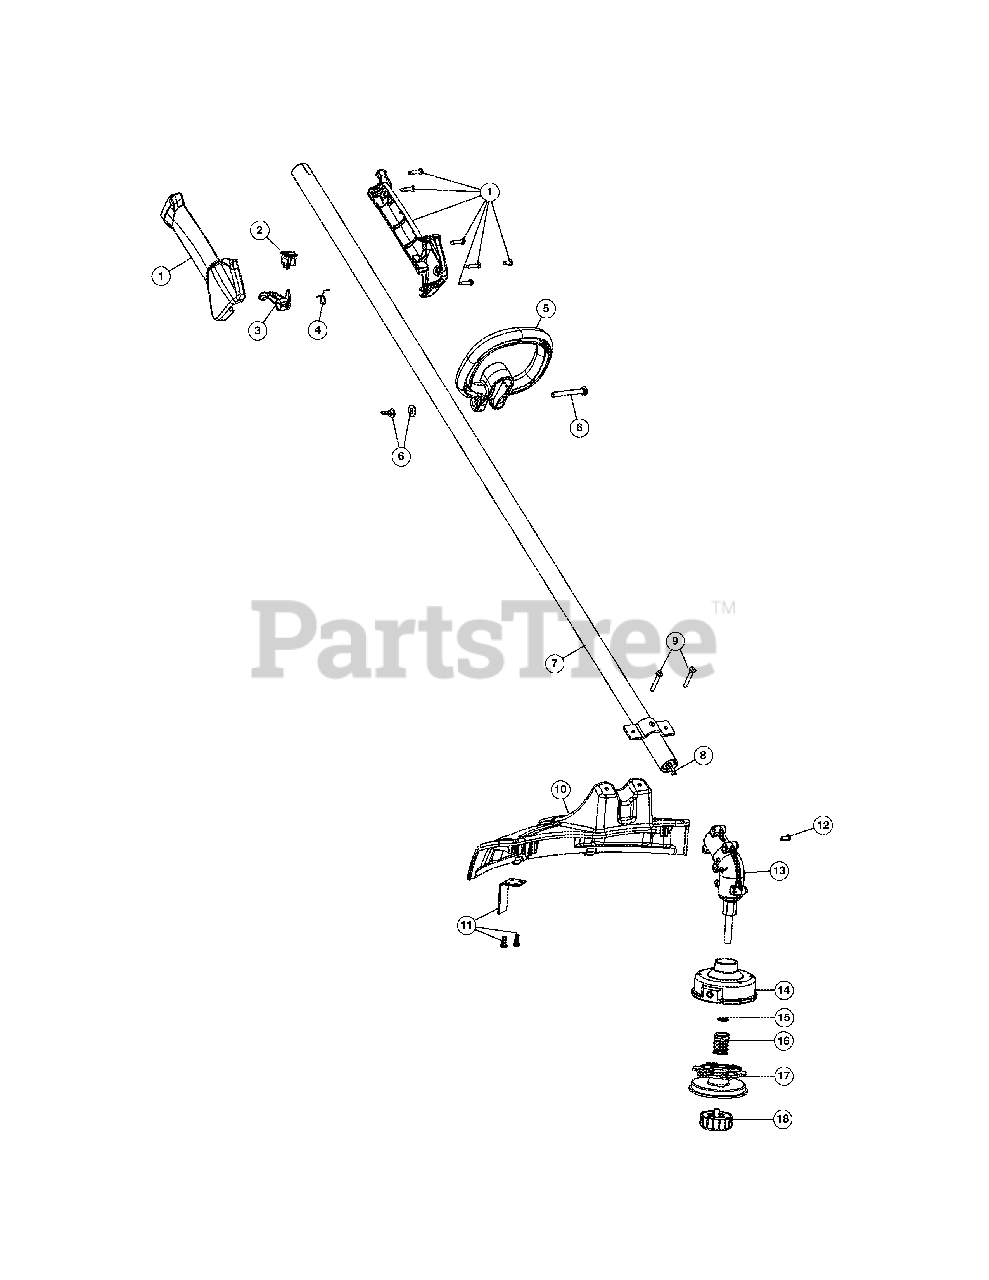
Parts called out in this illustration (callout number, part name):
1	Throttle Housing Assembly (includes 2-4)
3	Throttle Trigger
4	Throttle Trigger Spring
5	D-Handle (includes 6)
6	D-Handle Hardware Assembly
7	Drive Shaft Housing Assembly (includes 8)
8	Flexible Drive Shaft
9	Shield Mounting Screw
10	Shield Assembly (includes 9 & 11)
11	Blade Assembly
12	Anti-Rotation Screw
13	Gearbox Assembly (includes 14-18)
14	Outer Spool Assembly (includes 15)
15	Retainer
17	Inner Reel
18	Bump Head Knob Assembly
